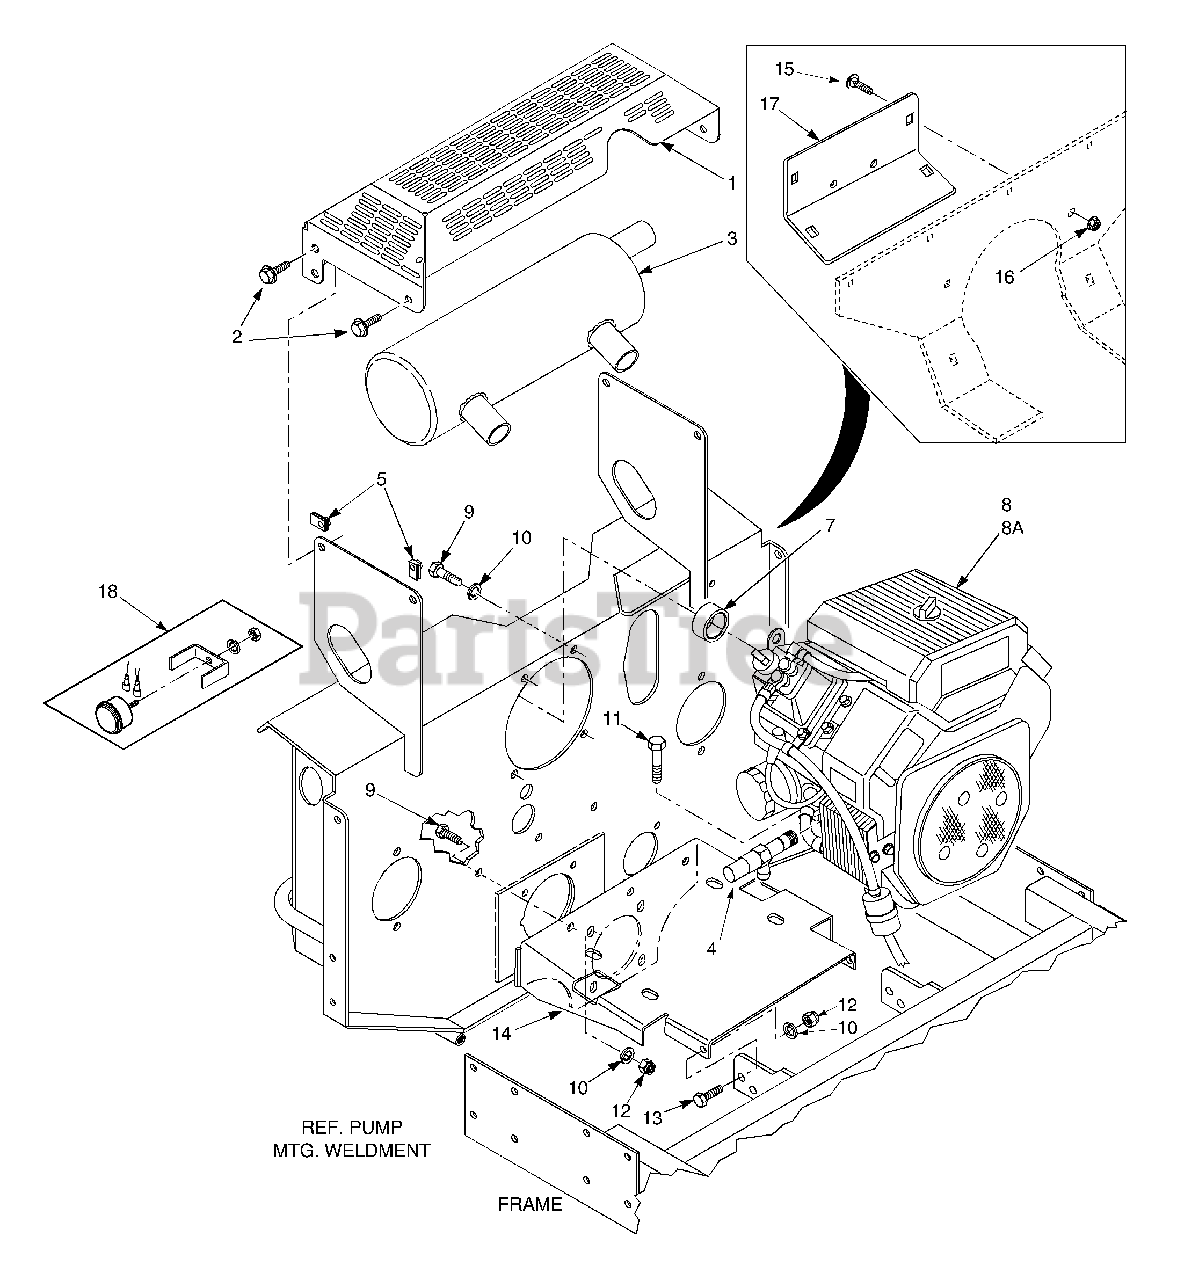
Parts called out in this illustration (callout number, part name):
1	Muffler Guard
2	Screw, Hex Serrated Flange 1/4-20 x 3/4"
3	Muffler, Part Of Engine (Available only through Kohler)
4	Oil Drain Extension
5	U-Nut, 1/4-20
6	Exhaust Elbow
7	Spacer, Engine (Kohler)
8	Engine, Kohler 25 CH (Available only through Kohler, Eng. Spec. PS-CH730-0066)
8A	Engine, Kohler 27 CH (Available only through Kohler, Eng. Spec. PS-CH740-0021)
9	Bolt, Hex Head 3/8-16 x 1"
10	Lockwasher, 3/8" Spring
11	Bolt, Hex Head 3/8-16 x 1-3/4"
12	Nut, Hex Elastic Stop 3/8-16
13	Bolt, Hex Head 3/8-16 x 1-1/4"
14	Plate, Engine Mounting
15	Bolt, Carriage 5/16-18 x 3/4"
16	Nut, Hex Serrated Flange 5/16-18
17	Rear Cover
18	Hour Meter
